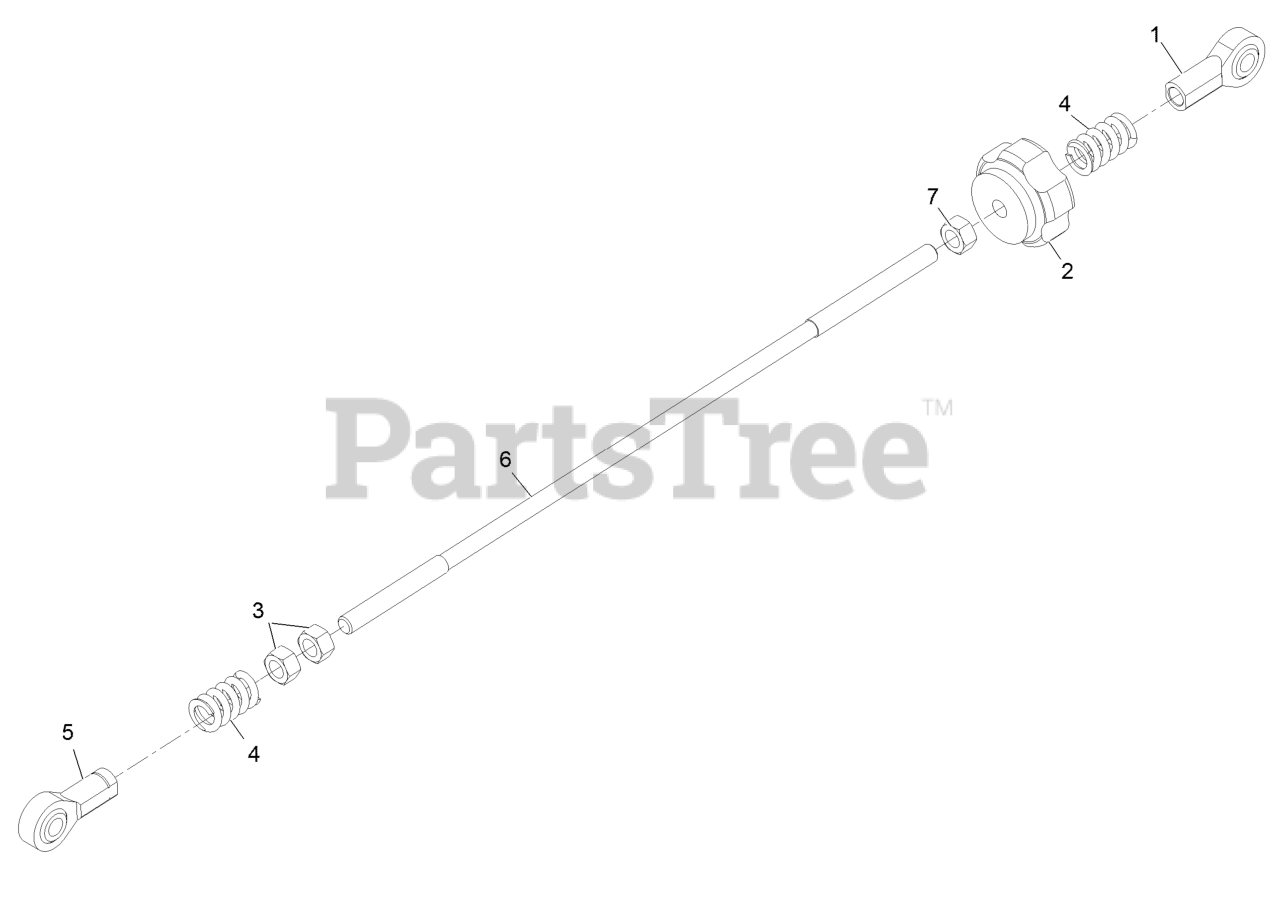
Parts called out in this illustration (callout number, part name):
1	BALLJOINT-RH
2	KNOB-TRACKING
4	SPRING-COMPRESSION
5	BALLJOINT-LH
6	LINK,TRACKING ROD XP
7	NUT-HEX
